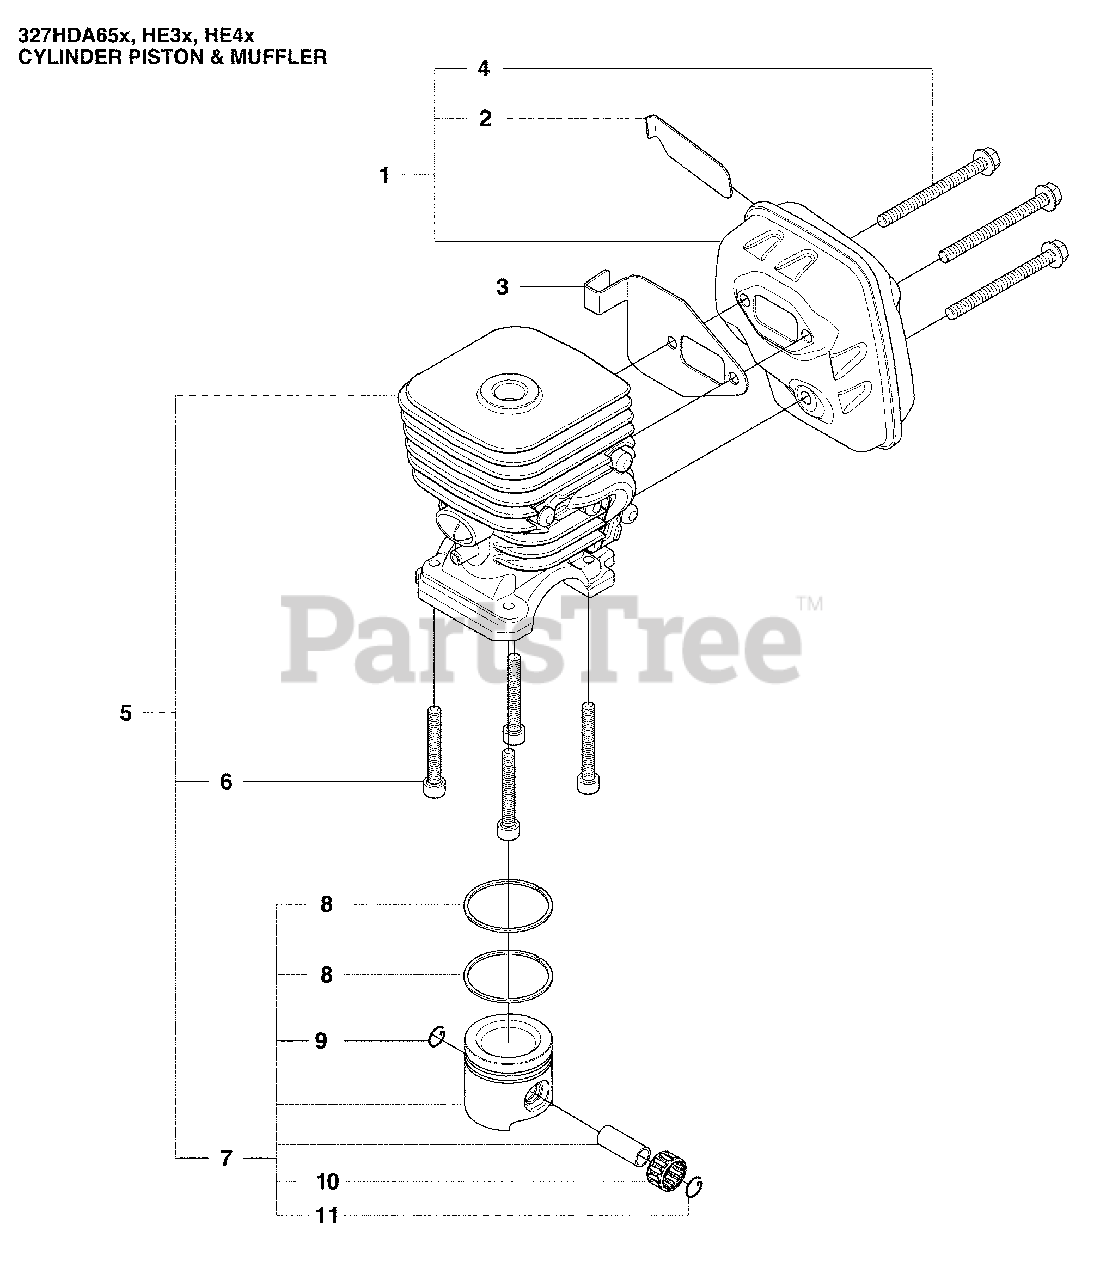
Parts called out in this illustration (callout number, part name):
1	Muffler Kit
2	Spark Arrestor Screen
4	Screw, Ehhfm
5	Cylinder, Complete
6	Screw, MC6S 5 X 35
8	Piston Ring
